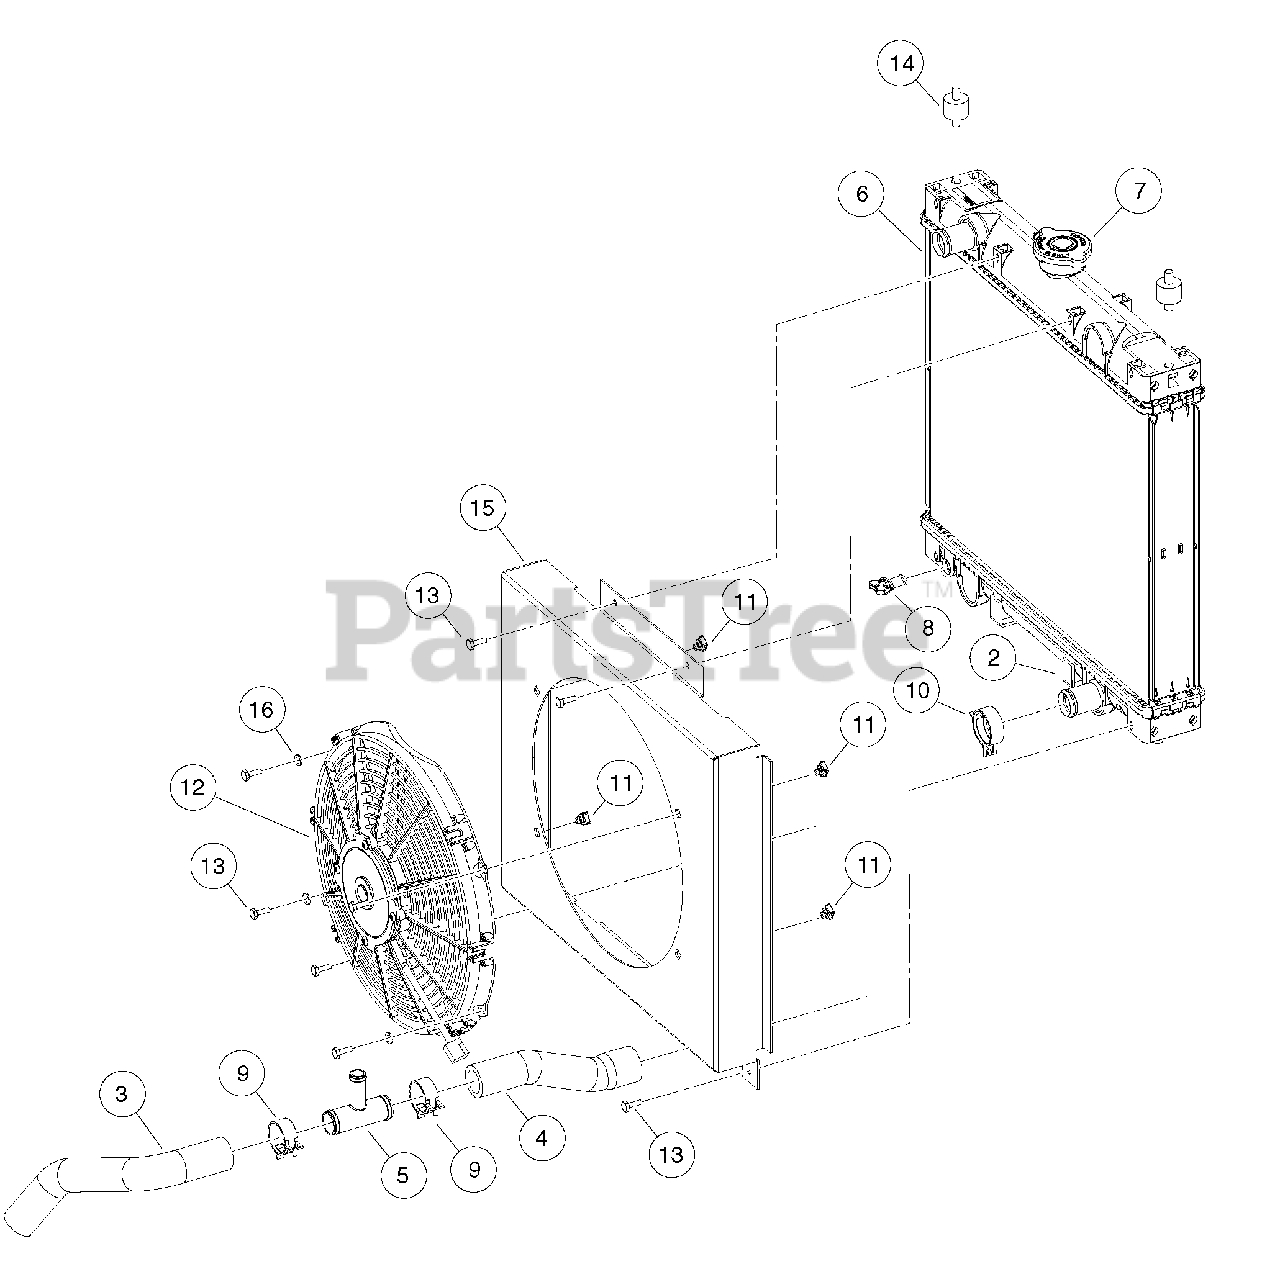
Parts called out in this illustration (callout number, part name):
1	Asm, Radiator
2	Tape, Vinyl Foam 1/8" x 3/4"
3	Hose, Coolant Lower Pipe
4	Hose, Coolant Lower Rad
5	Tee, Coolant Fill
6	Exchanger, Engine Coolant
7	Cap, Radiator
8	Drain Cock, Radiator
9	Clamp, Hose, Ctb 35mm
10	Clamp, Hose, Ctb 38mm
11	Nut, Self Retaining
12	Fan, Cooling 12 In Elect
13	Bolt, M6 X 1 X 16 Loctite
14	Isolator, Twin-Stud
15	Shroud, Radiator Fan
16	Washer, M6
